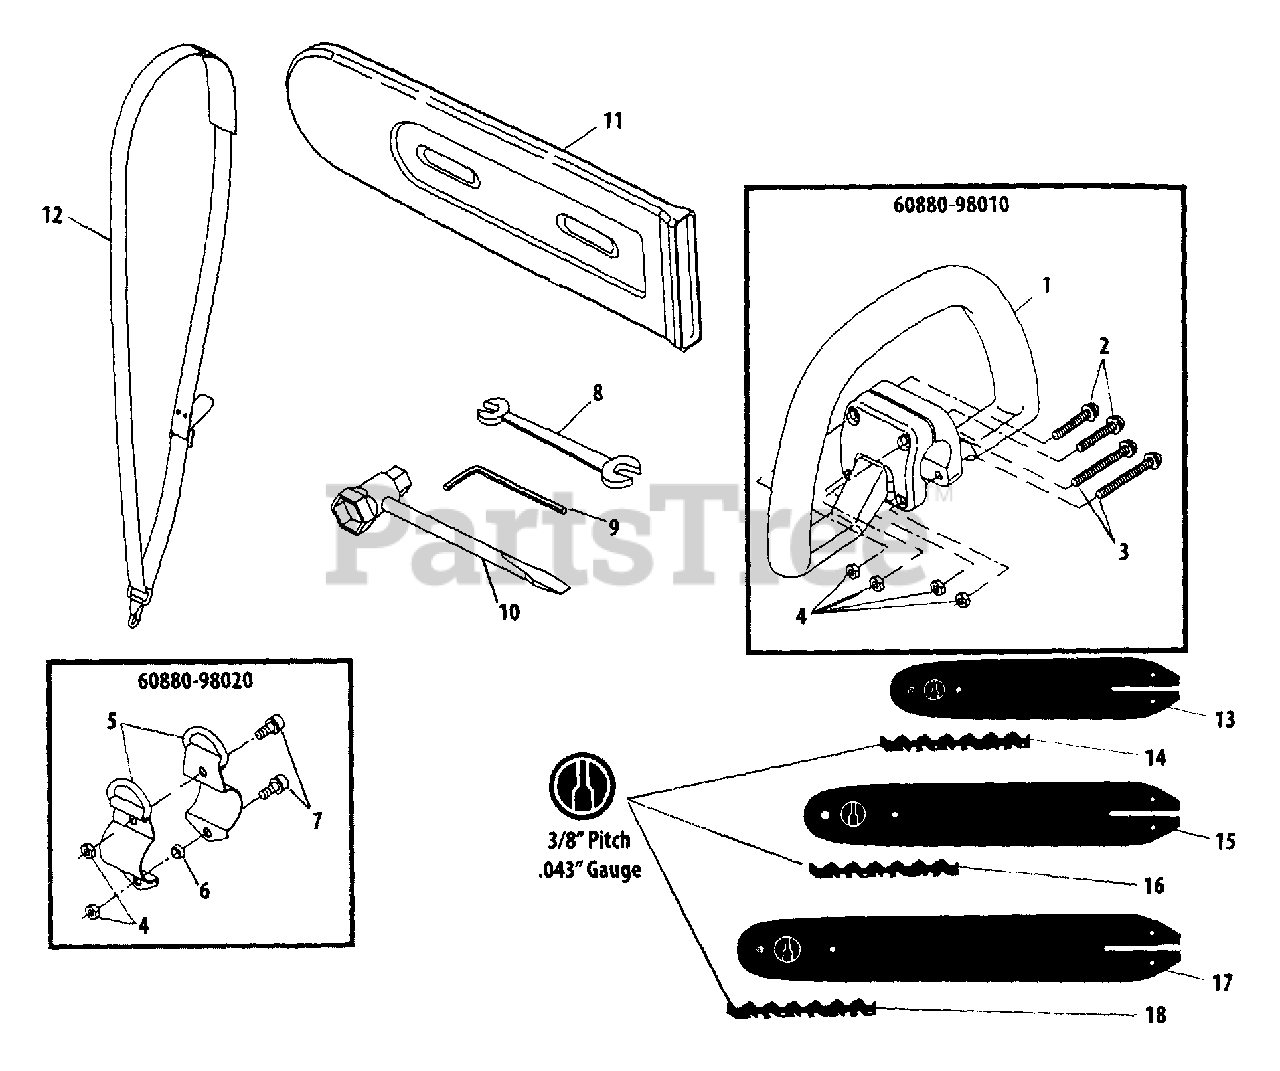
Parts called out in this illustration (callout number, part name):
2	SCREW - 5X30
3	SCREW - 5X45
7	SCREW - 5X12
8	SPANNER - 8X10mm
9	HEX KEY - 4mm
10	T-WRENCH
11	COVER, GUIDE BAR
12	STRAP ASSY
13	GUIDE BAR - 8" (20cm)
15	GUIDE BAR - 10" (25cm)
60880-98010	HANDLE ASSY
60880-98020	HANGER ASSY
